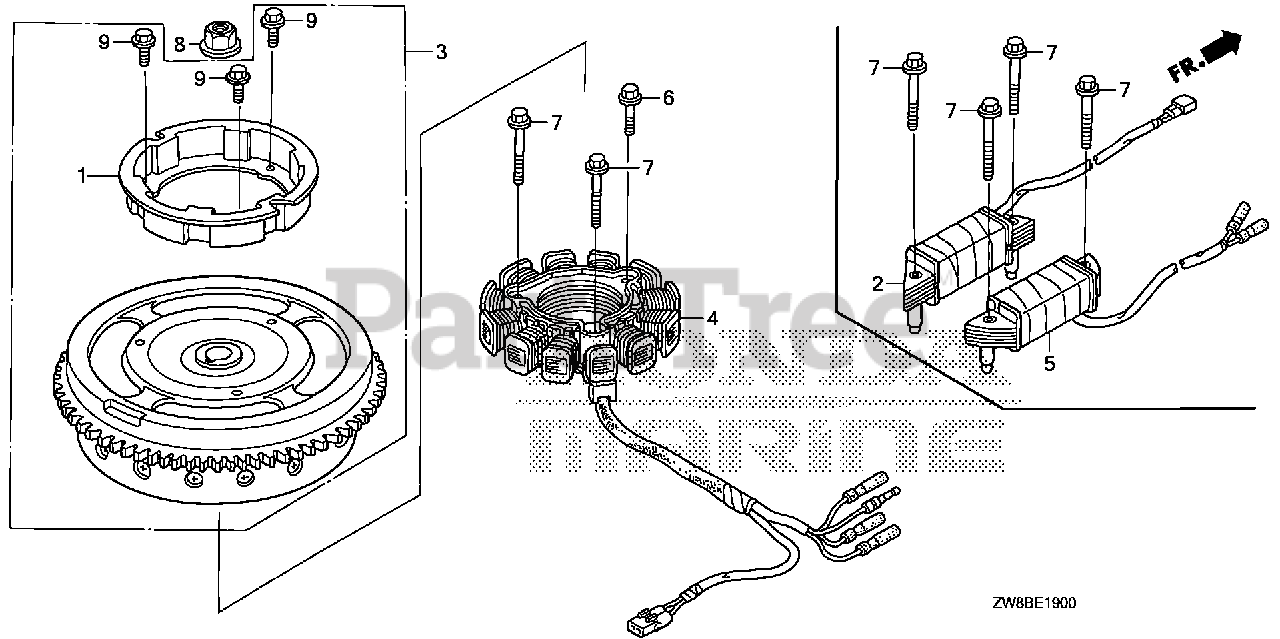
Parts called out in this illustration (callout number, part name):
1	PULLEY, STARTER
3	FLYWHEEL *TBLACK* (SELF STARTER) (BLACK)
4	COIL ASSY., CHARGE (12A)
6	BOLT, FLANGE (6X36) (CT200)
6	BOLT (6X36) (CT200)
7	BOLT, FLANGE (6X52) (CT200)
8	NUT, SPECIAL (14MM)
9	BOLT, FLANGE (6X10)
